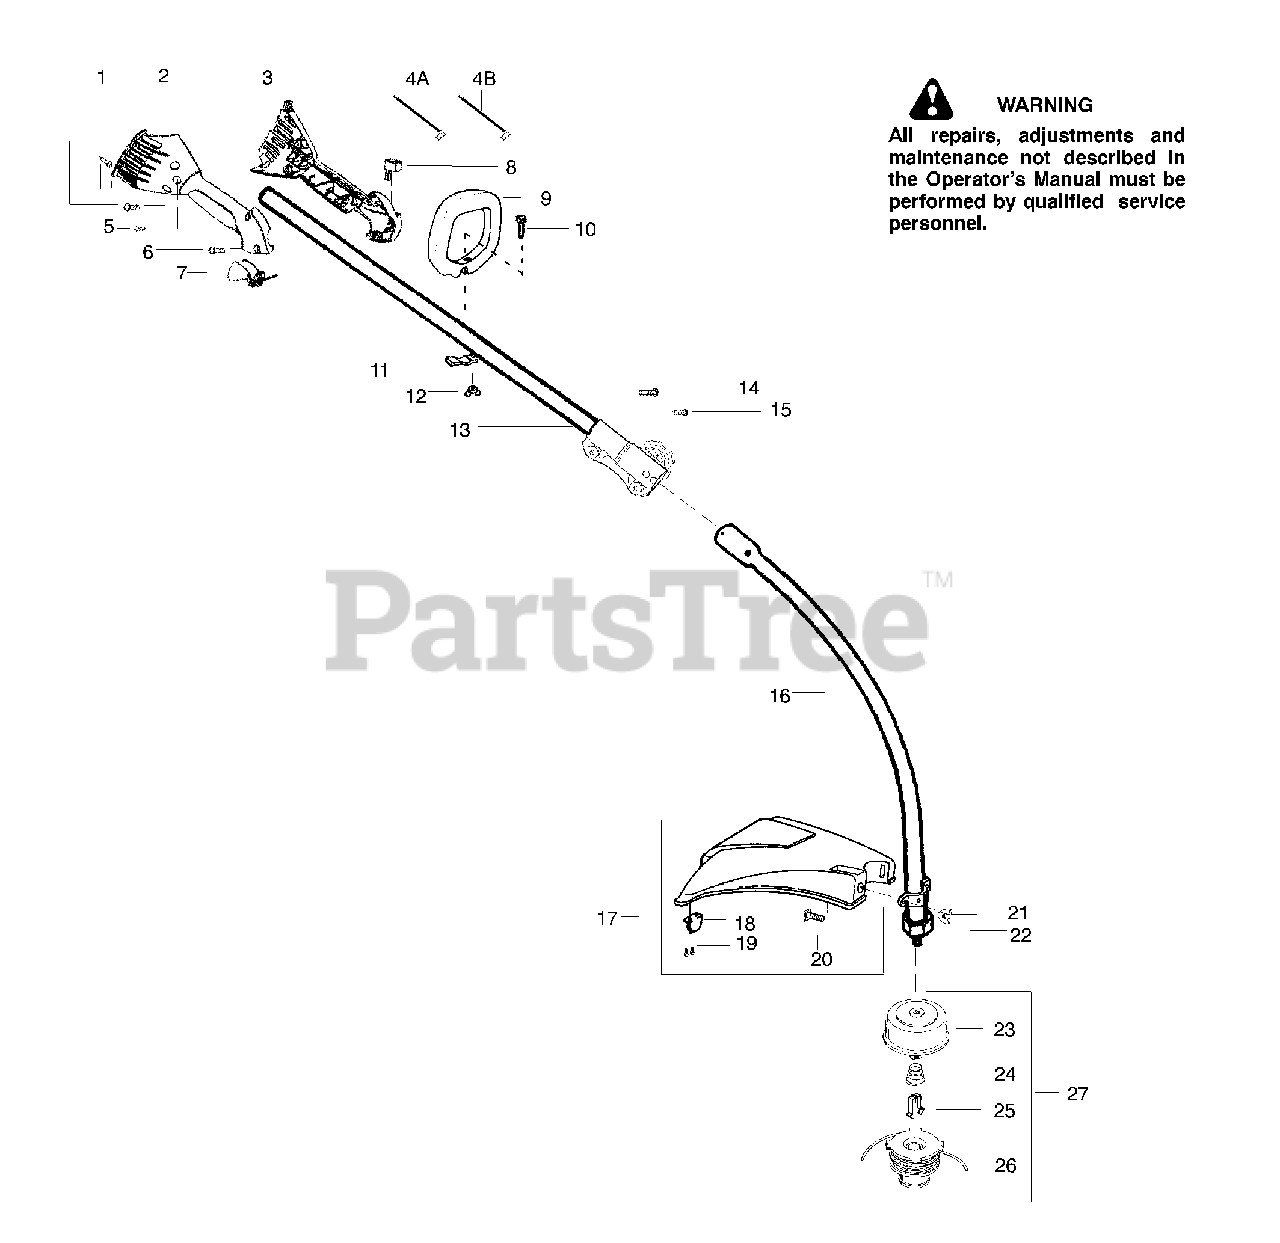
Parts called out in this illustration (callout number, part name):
1	Screw-handle/fan hsg
2	Hsg.-Throttle (Right)
3	Kit-Left Throttle Hsg.
4A	Assy-Front Wire Lower Front Wire
4B	Assy-Front Wire Upper Front Wire
5	Screw-Alignment
8	Kit-Switch
9	Assy-Handle-Assist
11	Clamp-Assist Handle
12	Wingnut
13	Assy-Upper Shaft
15	Screw-Alignment
16	Assy-Lower Shaft
17	Kit-Shield Ass'y.
18	Line Limiter
19	Screw-Line Limiter
23	Assy-Hub/Arbor
24	Spring-Return
25	Retainer-Spool
26	Assy-Wound Spool
27	Assy-TNG VI 3/8" -RH 2x
